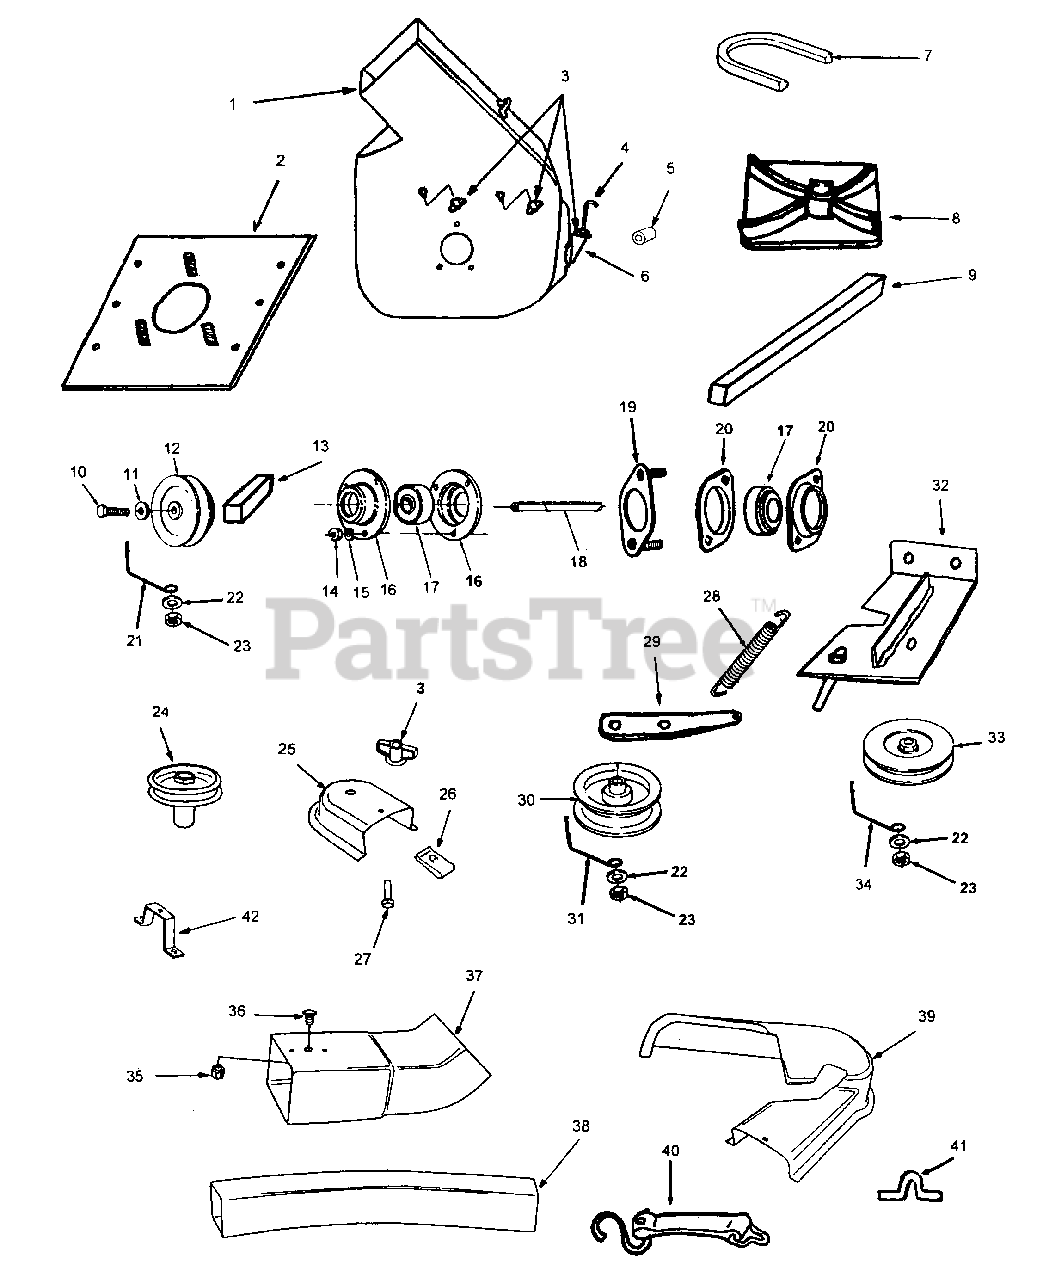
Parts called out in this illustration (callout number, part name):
1	Blower Hsg. w/Liner
2	Brg. Supt. Plate Assy.
3	Wing Nuts
4	Frt. Supt. Mounting Rod
5	Spacer, .320 X .625 X .92
6	Deck Stop Brkt.
7	Belt
8	Blade Implr.
9	Implr. Shaft Key
10	Hex Bolt 5/16-18 X 3/4 Lg.
12	Implr. Pulley
13	Implr. Pulley Key
15	Not Used In Application
16	Outer Brg. Supt. Flange
17	Implr. Shaft Brg.
18	Implr. Shaft
19	Supt. Brg, Flange
20	Inner Supt. Brg. Flange
21	Implr. Pulley Belt Guide
22	Wsh..305 I.d. X .740 o.d. X .062 Thk.
24	Driven Threaded Pulley
25	Small Belt Guard
26	U-Type Clip Nut 1/4-20
27	Hex Cap Screw 1/4-20 X 7/8
28	Idler Tension Spring
30	Flat Idler Pulley
31	Flat Idler Pulley Belt Guide
32	Idler Plate Assy.
33	V Idler Pulley
34	V Idler Pulley Belt Guide
37	Short Chute
39	Large Belt Guard
42	Blower Hsg. Retaining Brkt.
